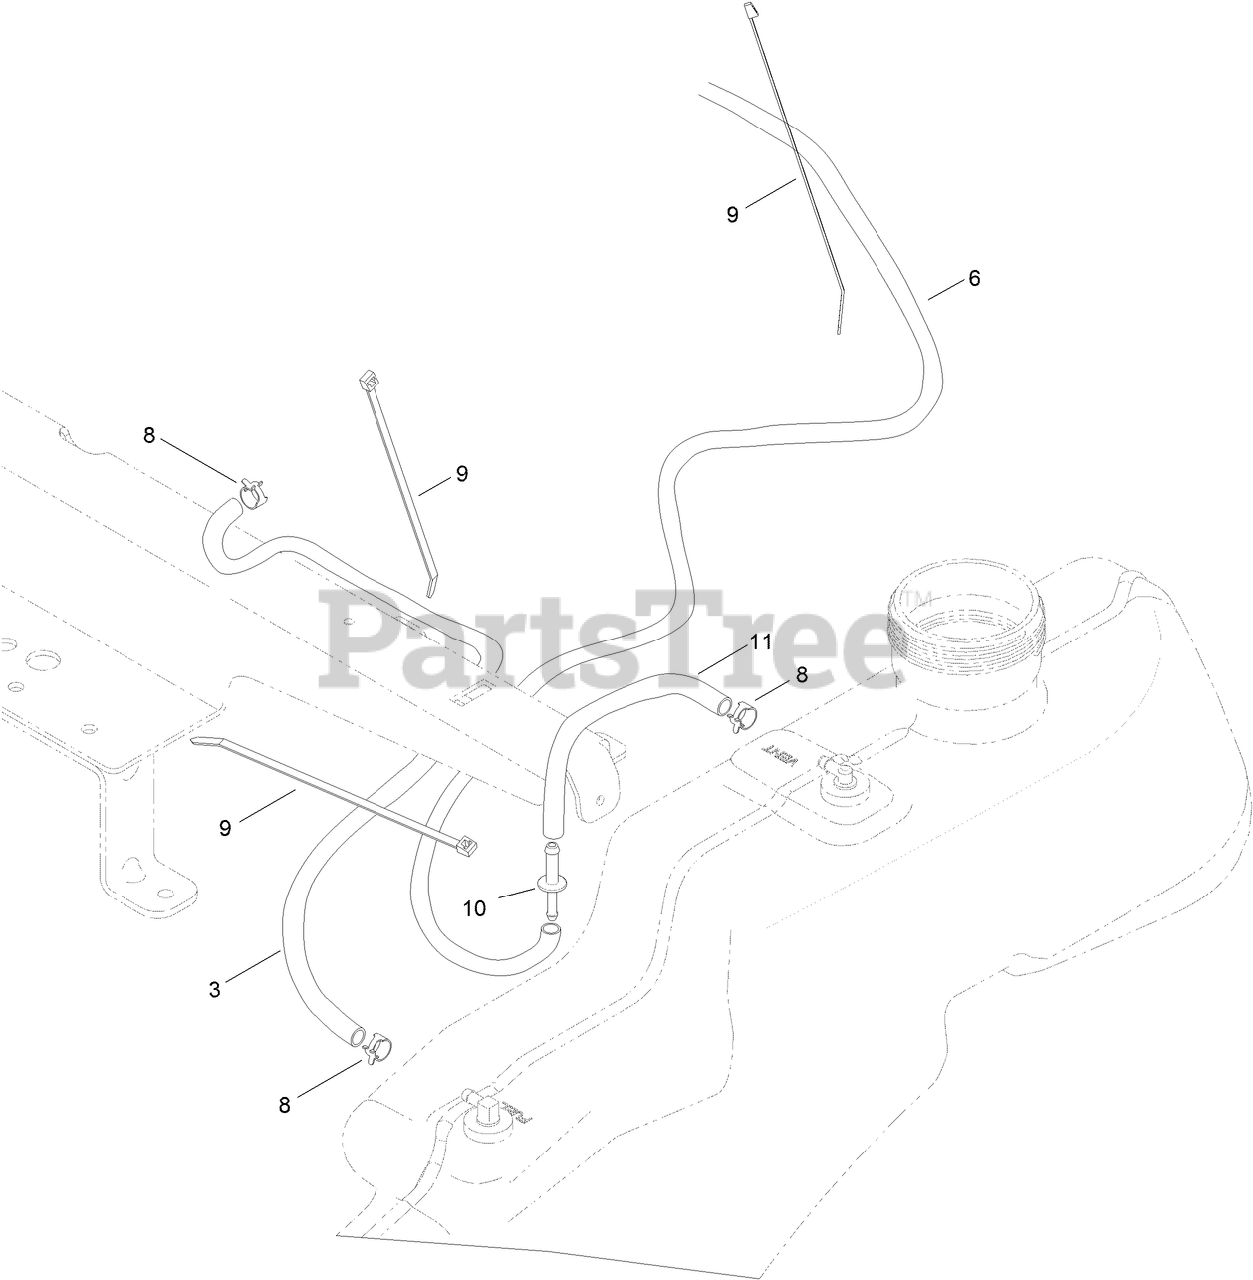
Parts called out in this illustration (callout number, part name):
3	HOSE-FUEL
6	HOSE-FUEL
8	CLAMP-HOSE
9	TIE-CABLE
10	ADAPTOR-ORIFICE
11	HOSE-FUEL
